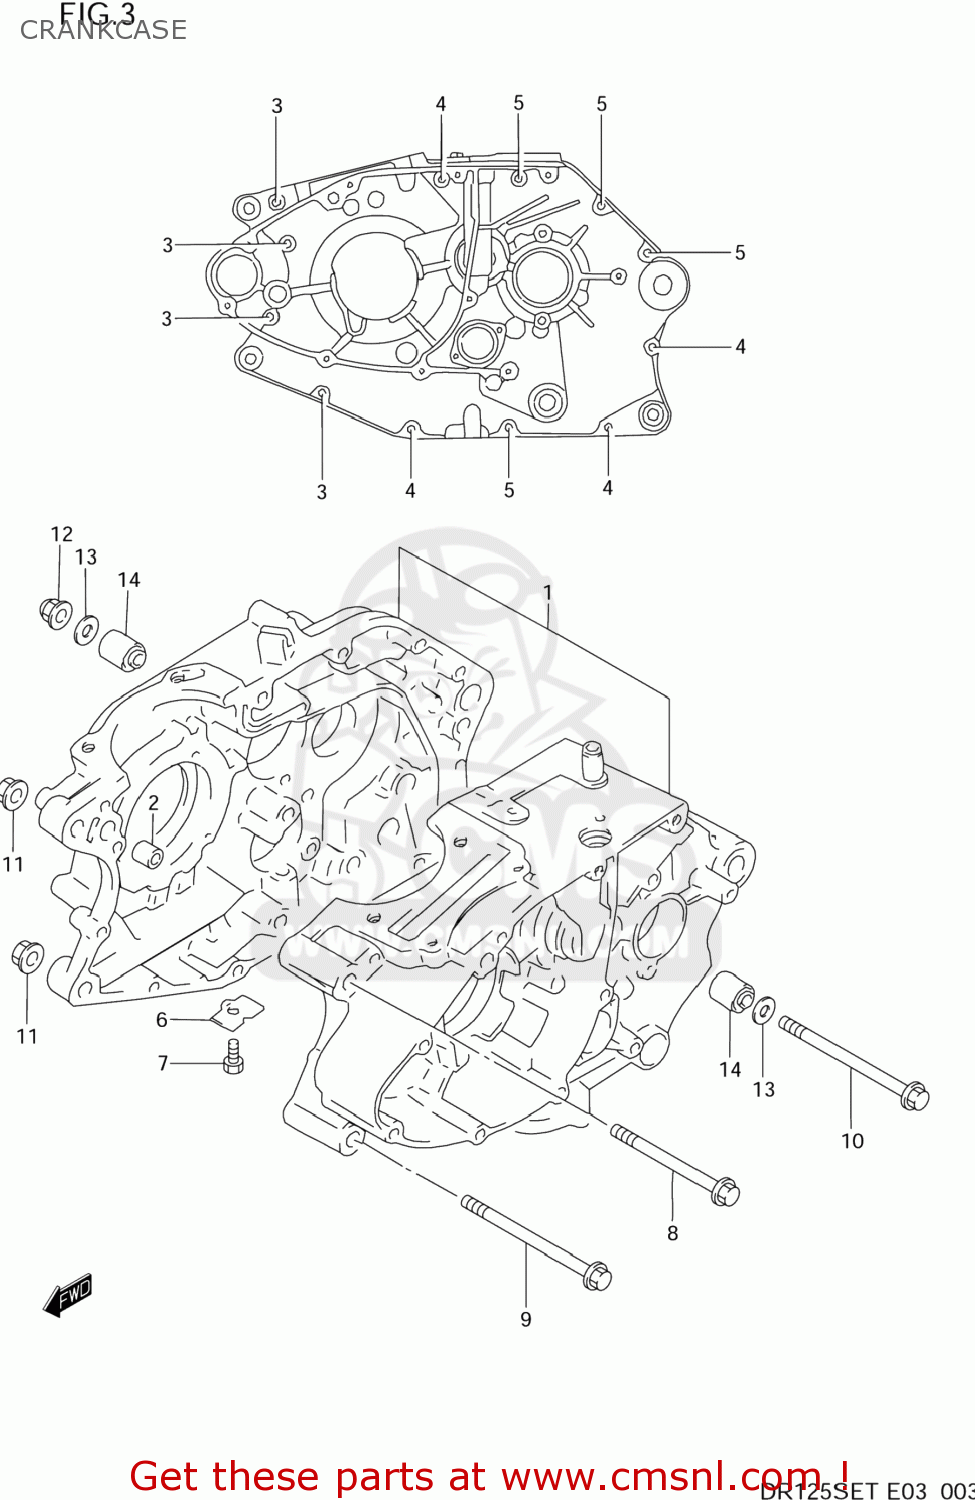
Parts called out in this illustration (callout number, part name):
1	CRANKCASE ASSEMBLY
2	PIN
3	BOLT
4	BOLT
5	BOLT
6	PLATE,OIL GALLERY PLUG
7	BOLT
8	BOLT(10X80)
9	BOLT(10X90)
10	BOLT(8X115)
11	NUT 10MM
12	NUT
13	WASHER
14	BUSH(8.4X18X16)
